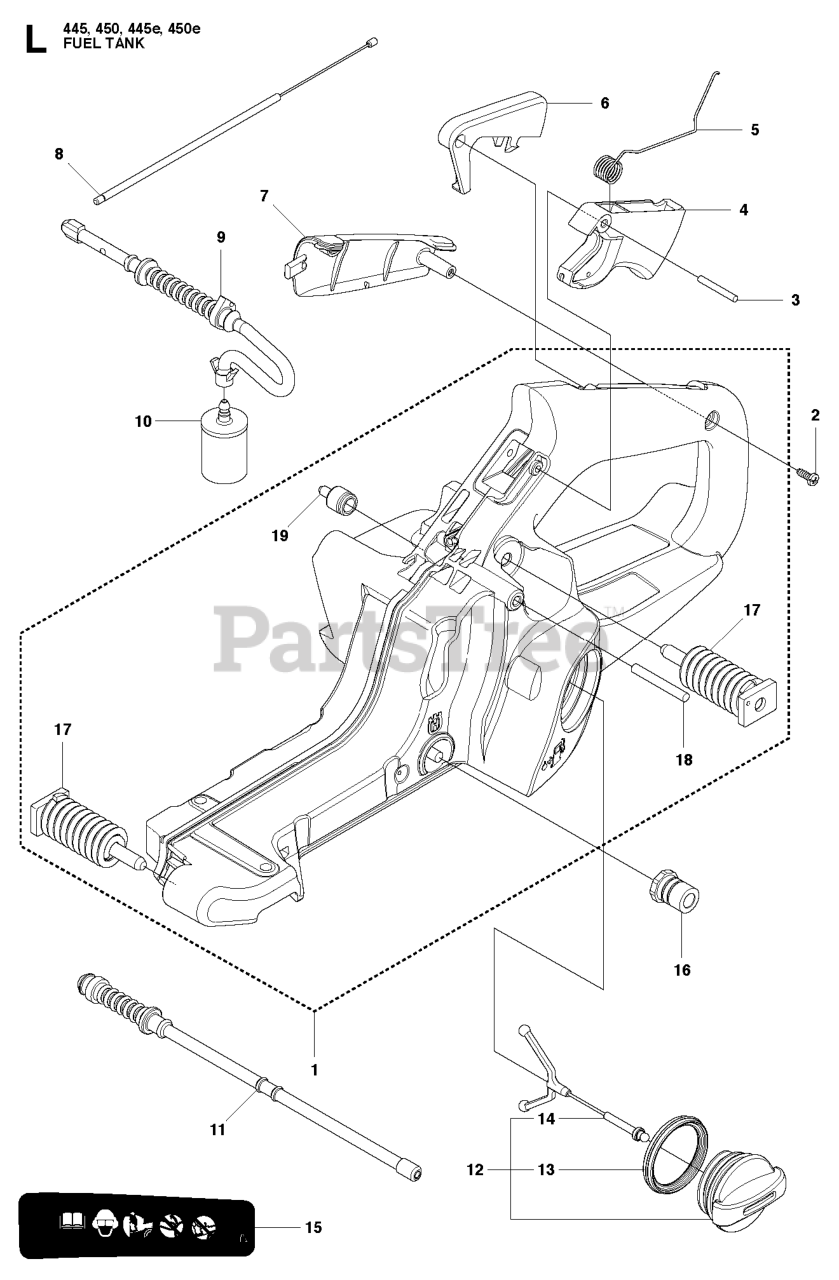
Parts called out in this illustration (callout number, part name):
1	FUEL TANK ASSY
4	THROTTLE TRIGGER
6	THROTTLE LOCKOUT
7	HANDLE INSERT
8	THROTTLE CABLE ASSY
10	RP FUEL FILTER
11	RP RETURN HOSE
12	TANK CAP ASSY
16	LATERAL SUPPORT
17	ANTI VIBRATIONS ELEMENT
18	GROOVED PIN
19	FUEL TANK VENT
